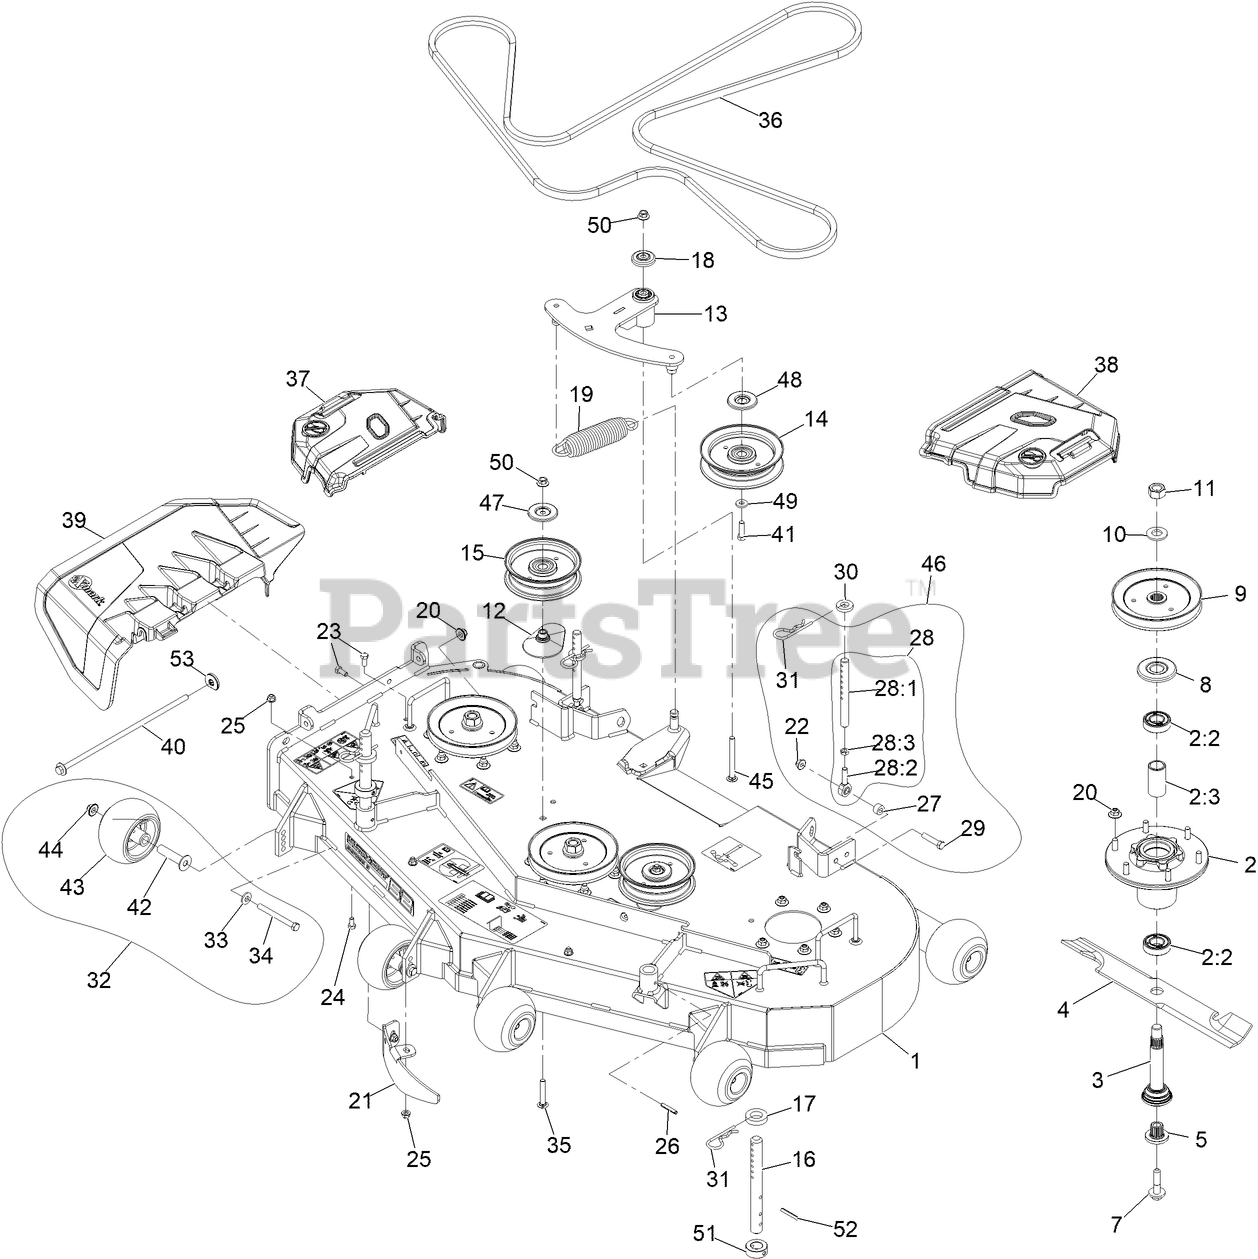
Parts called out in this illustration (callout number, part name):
1	ASM, DECK W/ DECALS, 52
2	ASM-CUTTER HSG WITH BEARINGS
2:2	BEARING-BALL
2:3	SPACER-BEARING
3	ASM-SPINDLE AND SEAL
5	BUSHING,SPLINED
7	SCREW,SEMS 1/2-20 X 2.19
8	GUARD,BEARING TOP .989
9	SHEAVE,BLADE DRIVE 6.50
11	NUT-HEX
12	SPACER-PULLEY
13	ASM, DECK IDLER
14	IDLER-PULLEY, FLAT
15	IDLER-PULLEY, FLAT 5.00X1.31
16	ROD, DECK SUPPORT TTS
17	SPACER-DECK SUPPORT
18	GUARD-TOP
19	SPRING-EXTENSION
20	Nut-Nyloc 3/8-16 Flg
21	BAFFLE, DOGLEG
22	NUT-HF, NI
23	SCREW-HH
24	SCREW-HH
25	NUT-HF, NI
28:1	LINK,SUPPORT
28:2	BALLJOINT
28:3	NUT-HJ
29	SCREW-HH
31	PIN,HAIR COTTER
32	KIT, ANTI-SCALP ROLLER
33	WASHER-BELLEVILLE
34	SCREW-HH 3/8-16 X 3 3/4 GR 8
35	BOLT-CARR, SHORT NECK
36	BELT, DECK
37	SHIELD, RT
38	SHIELD, LT
39	Chute-Deck Discharge
40	Pin, Chute
41	SCREW-HH
42	AXLE, ROLLER
43	ROLLER-SCALP, ANTI
44	Nut-Nyloc 3/8-16 Flg
45	SCREW-CARR
46	KIT,SUPPORT LINK W/PIN
47	SHIELD-DUST
48	SHIELD-GUARD, DUST
51	COLLAR, DECK HEIGHT PIN
52	PIN-ROLL
53	Retainer, Chute
